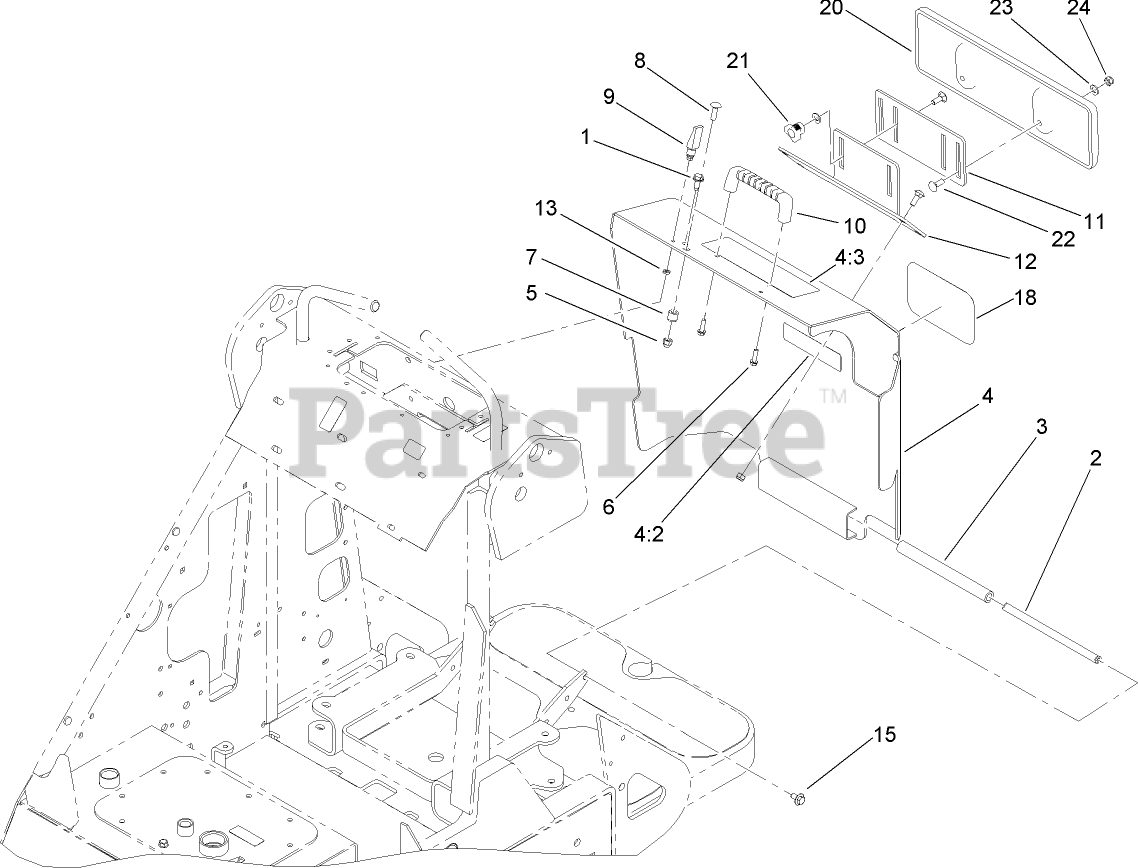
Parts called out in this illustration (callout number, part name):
1	SCREW-HWHTF
2	BAR-HINGE
3	HOSE-HINGE
4	COVER ASM
4:2	DECAL-DANGER
4:3	DECAL-DANGER
5	NUT-LOCK, CAP
6	SCREW-HWH
7	SPACER-GUIDE
8	SCREW-CARR
9	LATCH-SWELL
10	HANDLE-DOOR
11	PLATE-ADJUSTING
12	BRACKET-SUPPORT, THIGH
13	WASHER
15	SCREW-HHF
18	DECAL
20	SUPPORT-THIGH
21	Knob-Adjustment
22	SCREW-CARR
23	WASHER-FLAT
24	NUT-LOCK, NI
